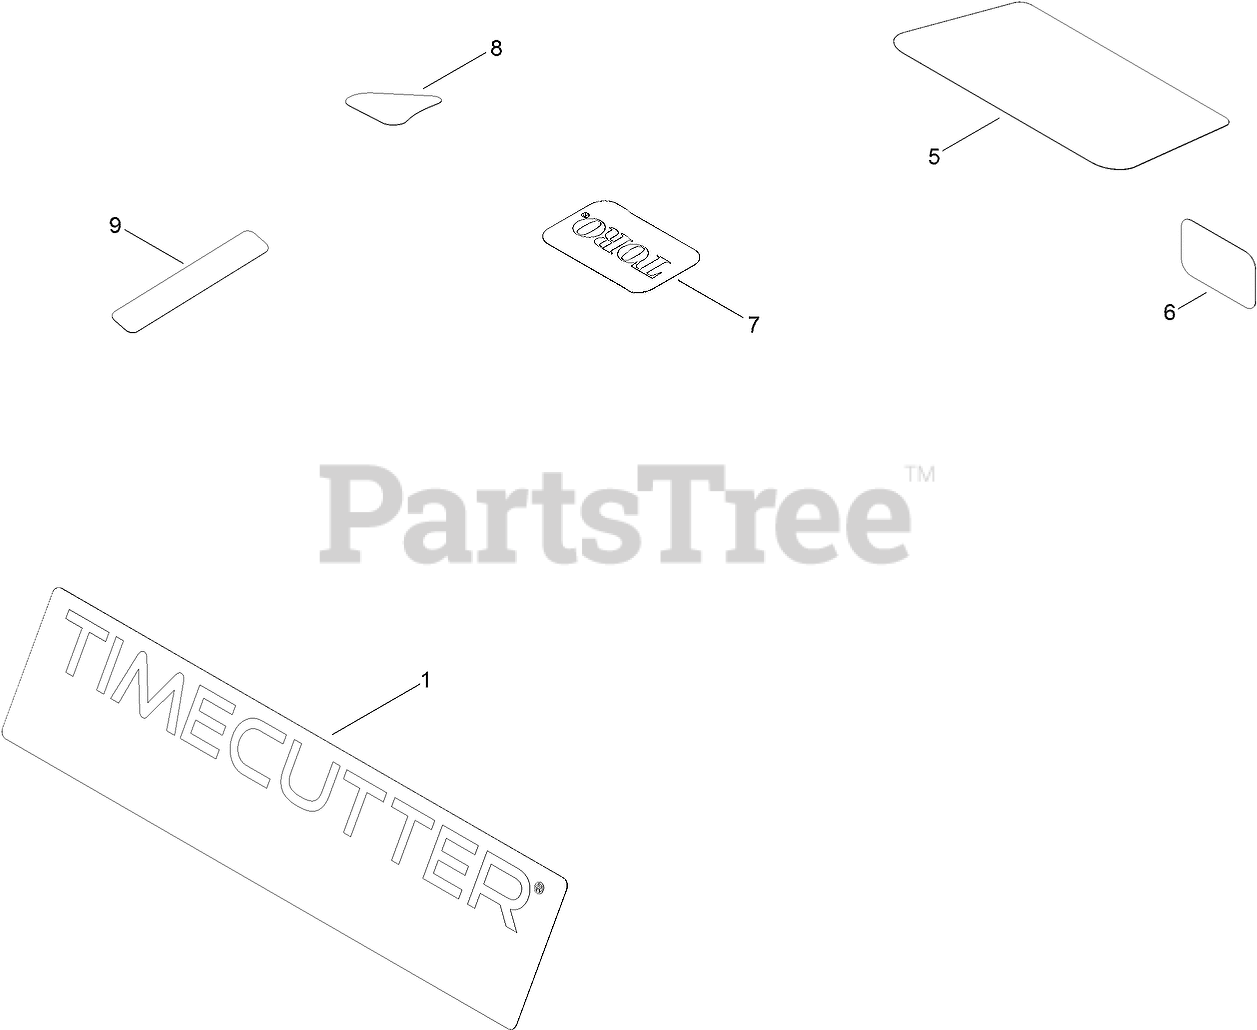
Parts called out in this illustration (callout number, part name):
1	DECAL-TIMECUTTER
5	DECAL-ENGINE
6	PLACARD-INTAKE
8	DECAL-DRAIN, OIL
9	DECAL-SHUTDOWN
